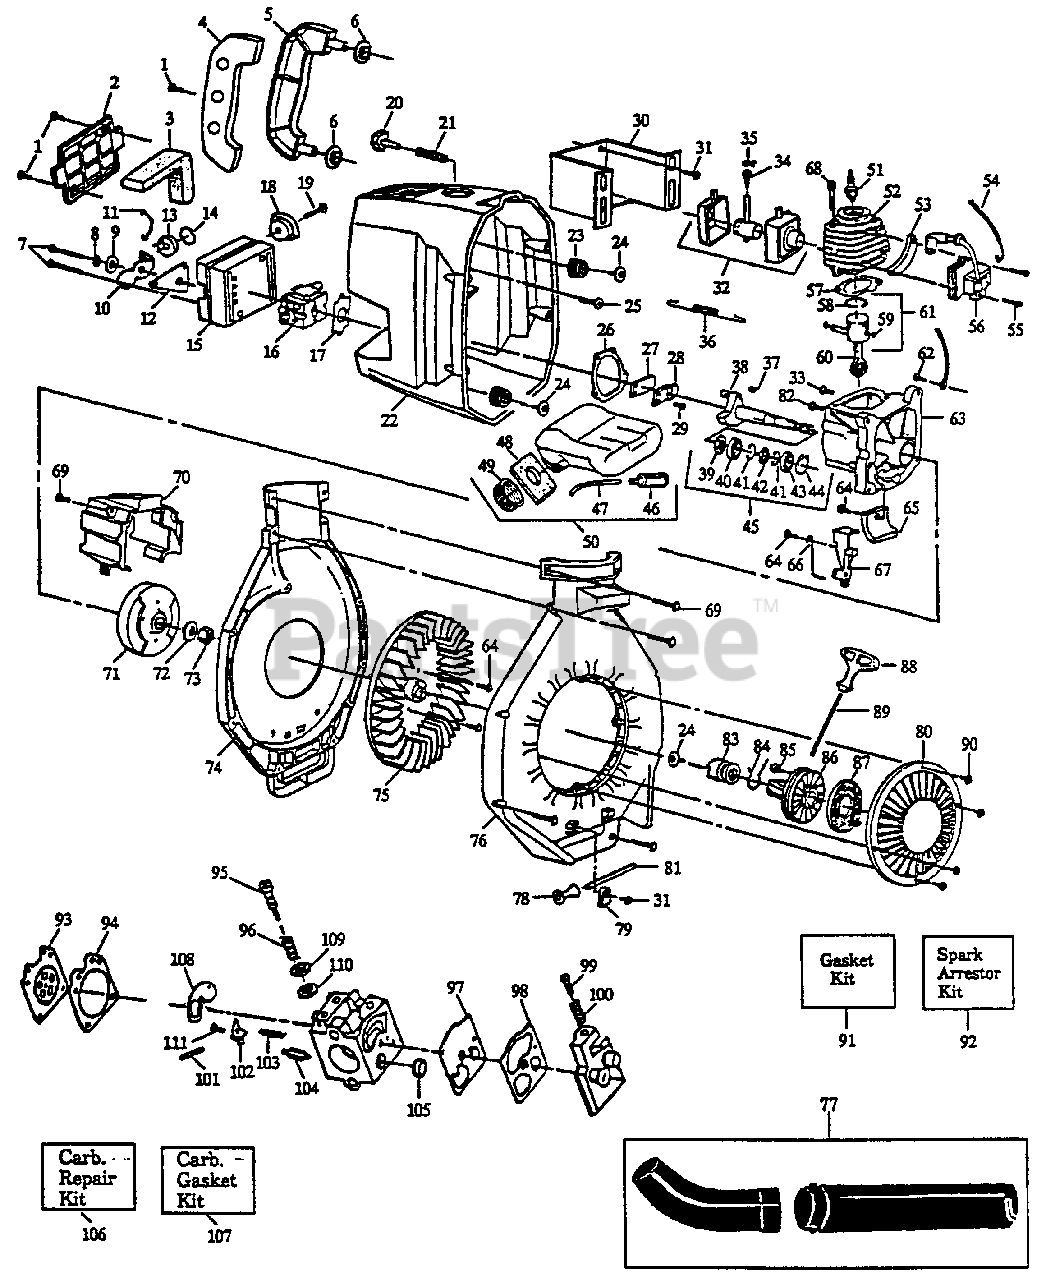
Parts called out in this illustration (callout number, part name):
2	Air Filter Cover
3	Air Filter
4	Handle Cover
6	Handle Isolator
8	Choke Spacer
9	Wave Washer
10	Choke Shutter
11	Throttle Wire
12	Choke Mtg. Plate
14	Wave Washer (Knob)
15	Air Box
16	Carburetor (WA-207A)
17	Carburetor Gasket
18	Throttle Knob
27	Reed Valve
29	Screw
30	Heat Shield
34	Spark Arrestor Screen
35	Spark Arrestor Clamp
36	Muffler Spring
38	Crankshaft Ass'y.
40	Inner Bearing
42	Crankshaft Seal
43	Outer Bearing
44	Retaining Ring
45	Crankcase/Crankshaft Ass'y.
46	Fuel Pick-Up Ass'y.
47	Fuel Line Kit
49	Fuel Cap
50	Fuel Tank Ass'y.
51	Spark Plug
52	Cylinder
54	Leadwire Switch
56	Ignition Module
57	Gasket
58	Piston Ring
60	Piston Rod
61	Piston Kit
63	Crankcase Ass'y.
69	Screw
74	Blower Housing (Upper)
76	Blower Housing (Lower)
77	Blower Tube Kit
80	Pulley Housing
84	Drag Element
86	Starter Pulley
87	Starter Spring
88	Starter Handle
91	Gasket Kit
92	Spark Arrestor Kit
93	Metering Diaphragm
94	Metering Diaphragm Gasket
95	Mixture Needle
96	Mixture Needle Spring
97	Fuel Pump Diaphragm
98	Fuel Pump Gasket
99	Idle Speed Screw
100	Idle Speed Spring
101	Metering Lever Pin
102	Metering Lever
103	Metering Lever Spring
104	Inlet Needle Valve
105	Fuel Inlet Screen
106	Carb. Kwik Repair Kit
107	Carb. Gasket/Diaphragm Kit
108	Circuit Plate Gasket
109	Mixture Needle Washer
110	"O" Ring Mixture
111	Metering Lever Pin Screw
